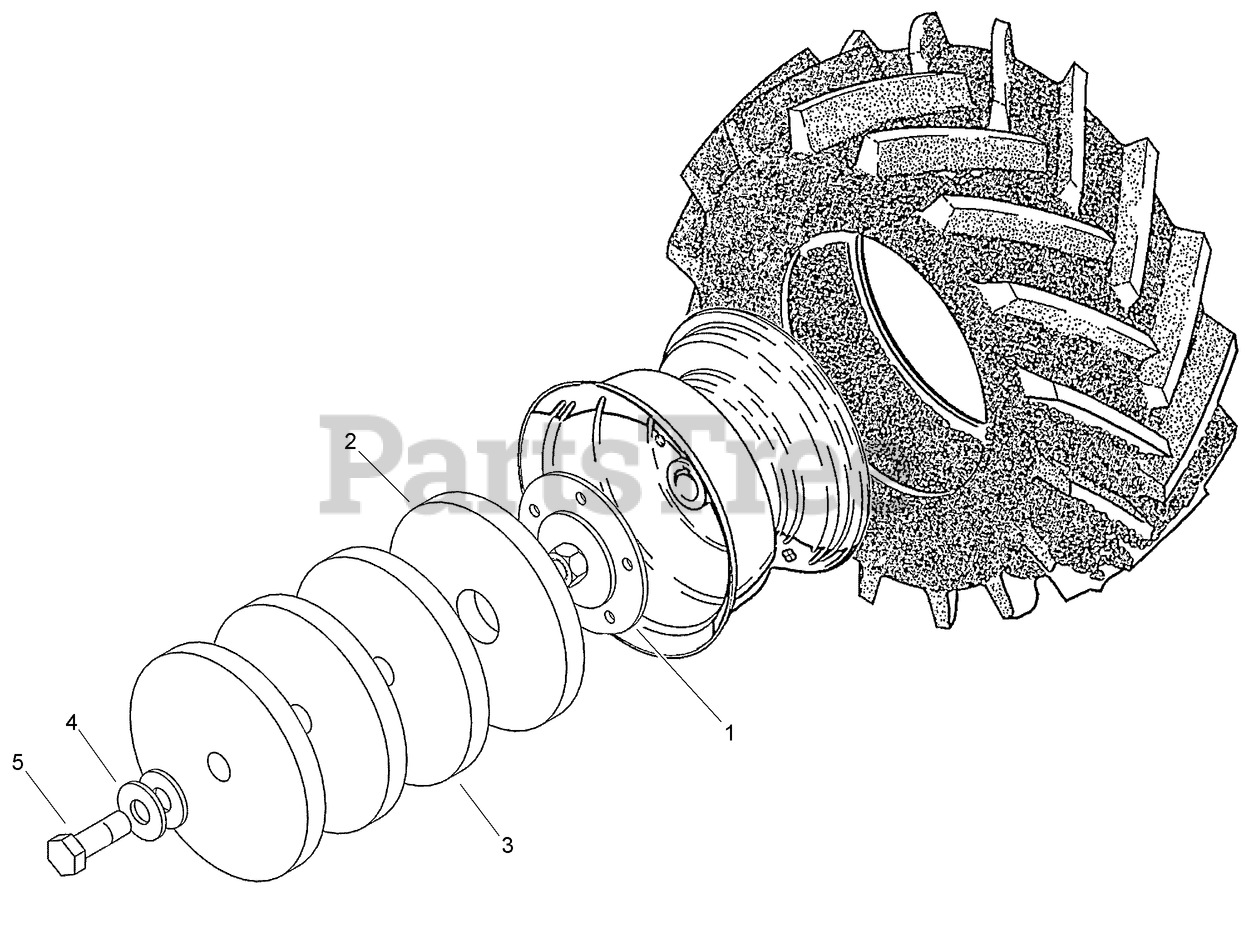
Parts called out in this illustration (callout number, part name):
1	PLATE-RETAINER
2	PLATE - Wheel Weight, Inner
3	PLATE - Wheel Weight
4	WASHER-FLAT
